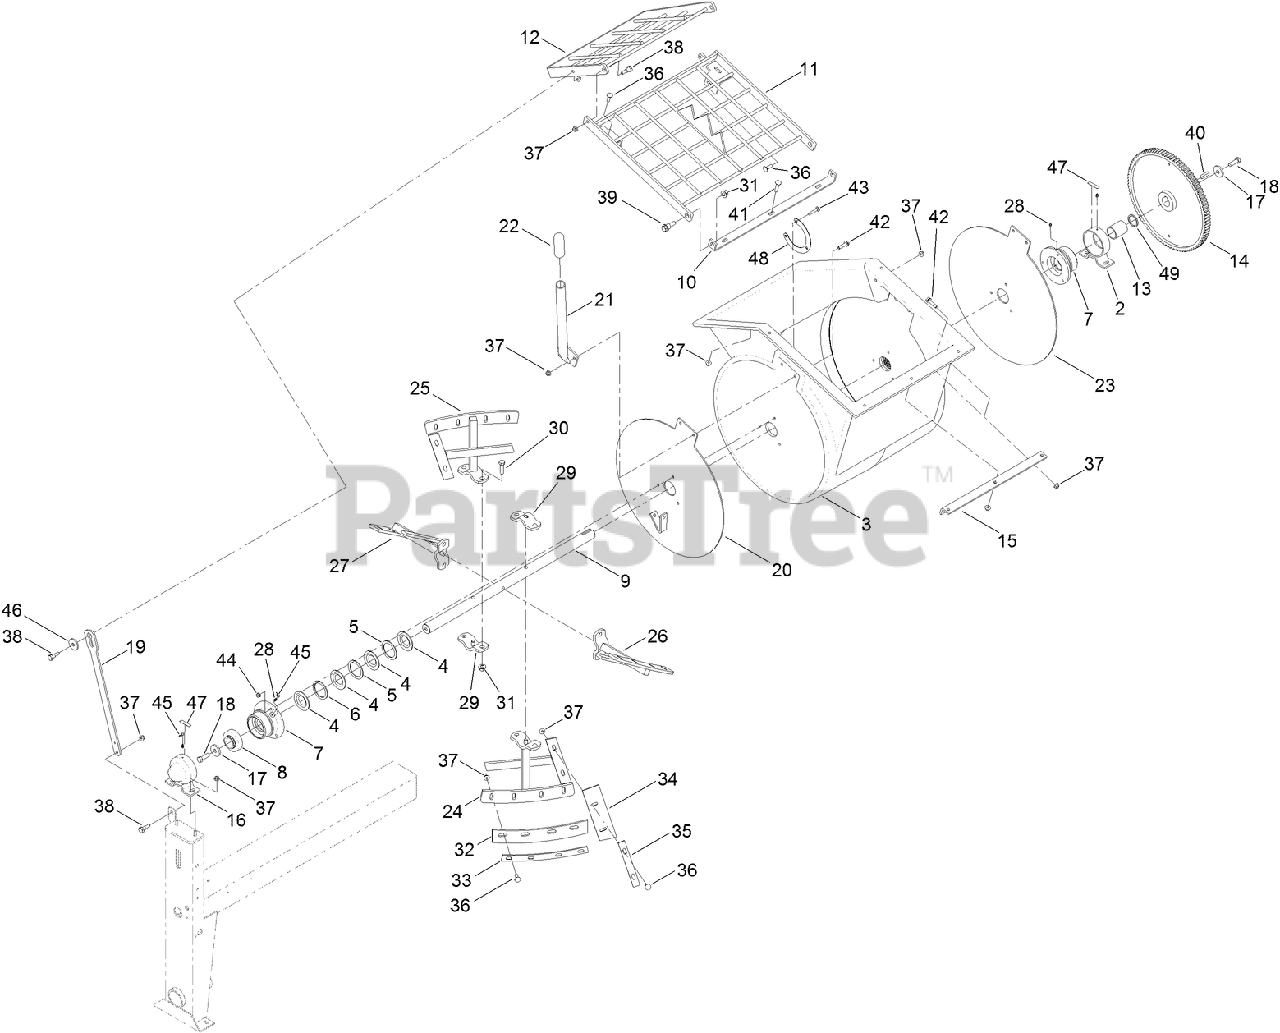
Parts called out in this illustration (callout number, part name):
2	TRUNNION
4	SEAL-DRUM
5	WASHER-FLAT
6	WASHER-SPLIT
7	HOUSING-BEARING
8	BEARING-BALL
9	SHAFT-DRUM
10	BRACKET-GUARD, MOUNT
11	GUARD-DRUM
12	GUARD-MOVEABLE
13	SPACER-SHAFT, DRUM
14	GEAR-94 TEETH
15	BRACKET-SUPPORT, GUARD
16	TRUNNION-CAPPED
17	WASHER-FLAT
18	SCREW-HH
19	BAR-GUARD, LIFTER
20	END-DRUM
22	GRIP-HAND
23	END-DRUM
28	FITTING-GREASE
30	SCREW-HH
31	NUT-LOCK
32	BLADE-RUBBER, LONG
33	BAR-BACKER, LONG
34	BLADE-RUBBER, SHORT
35	BAR-BACKER, SIDE
36	BOLT-CARR
37	NUT-HF, NI
38	BOLT-SHOULDER
39	SCREW-SHOULDER, HHF
40	KEY-SQUARE
41	SCREW-CARR
42	SCREW-HHF
43	SCREW-CARR
44	NUT-HF, NI
45	CAP-PLUG
46	Washer-Thrust
47	DECAL-GREASE
48	SPACER-BOLT
49	SPACER-SHAFT, DRUM
